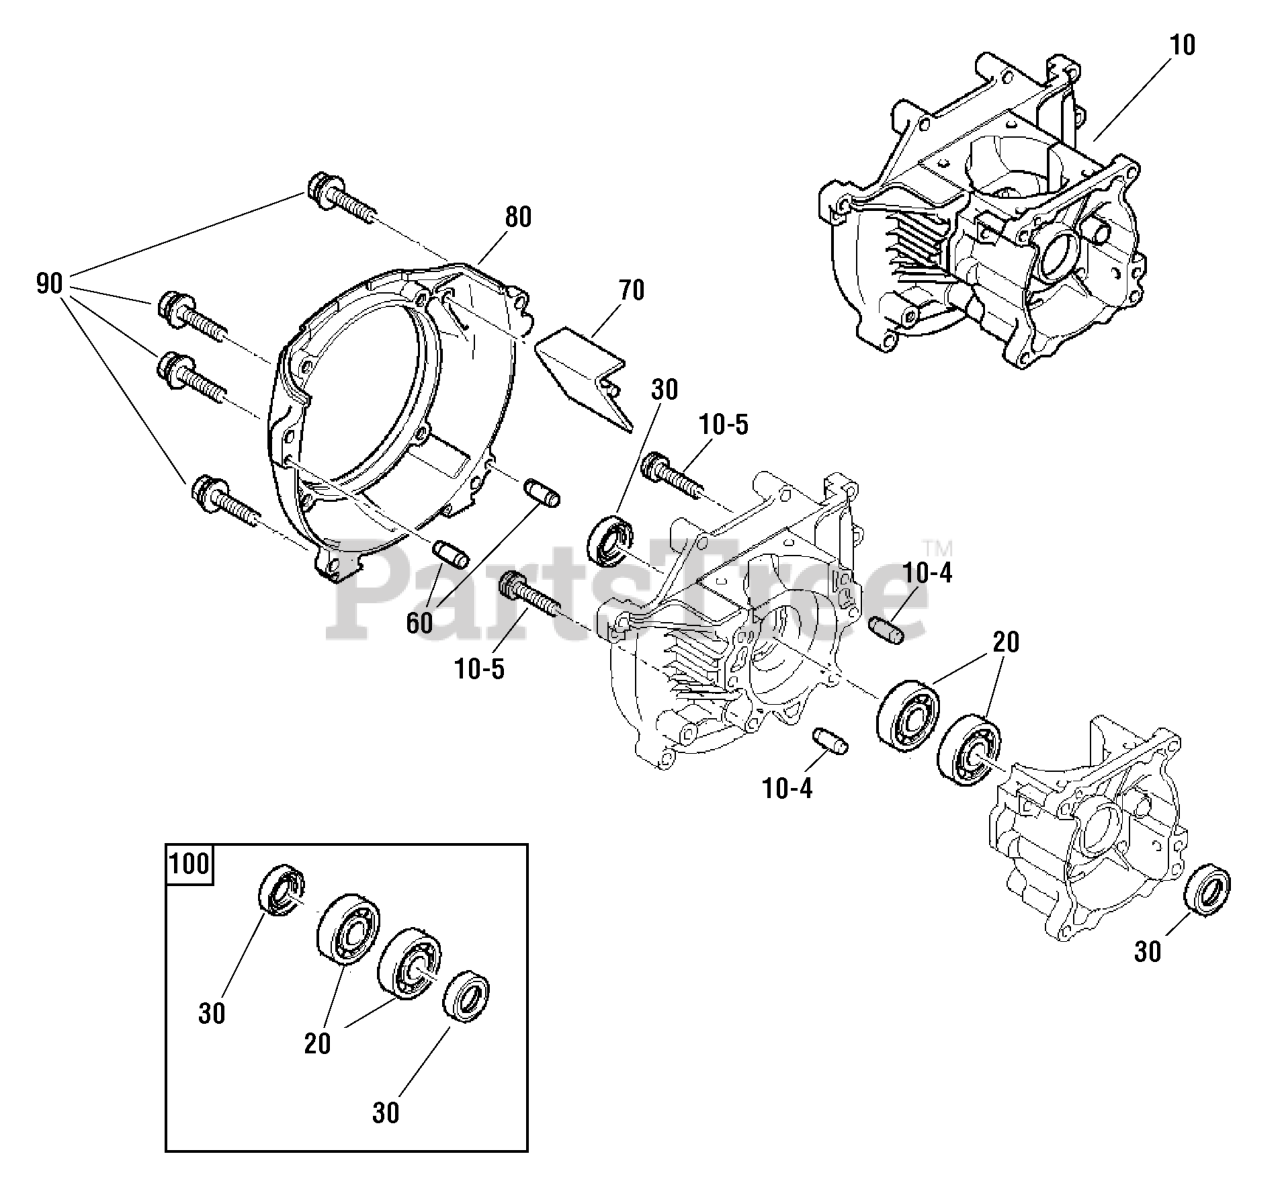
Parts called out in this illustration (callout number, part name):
10	CRANKCASE ASSEMBLY
10-4	PIN, Dowel
10-5	SCREW & WASHER
20	BEARING, Ball
30	OIL SEAL
60	PIN, Dowel
70	NOSE
80	CASE, Fan
90	BOLT & WASHER
100	KIT, Bearing Seal & Gasket
